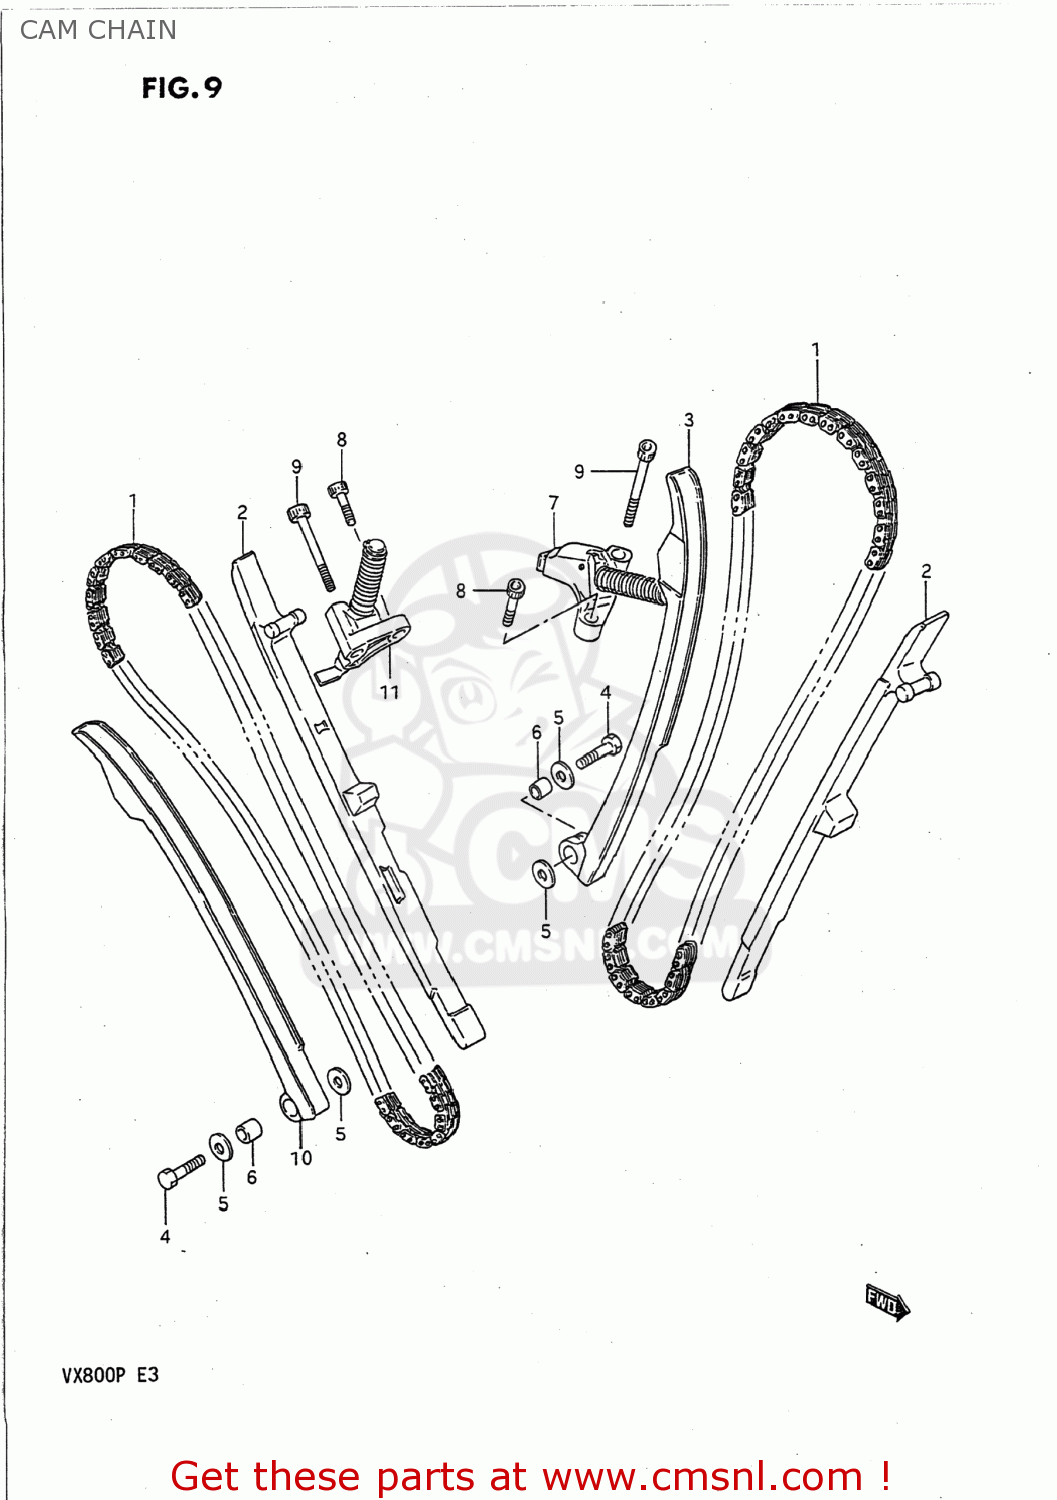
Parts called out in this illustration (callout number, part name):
1	CHAIN,CAMSHAFT DRIVE
2	GUIDE,CAM CHAIN
3	TENSIONER,FR CAM CHAIN
4	BOLT(6X26)
5	WASHER
6	SPACER(6X11X11)
7	ADJUSTER ASSEMBLY,FRONT TENSIONER
8	BOLT
9	BOLT
10	TENSIONER,RR CAM CHAIN
11	ADJUSTER ASSEMBLY,REAR TENSIONER
